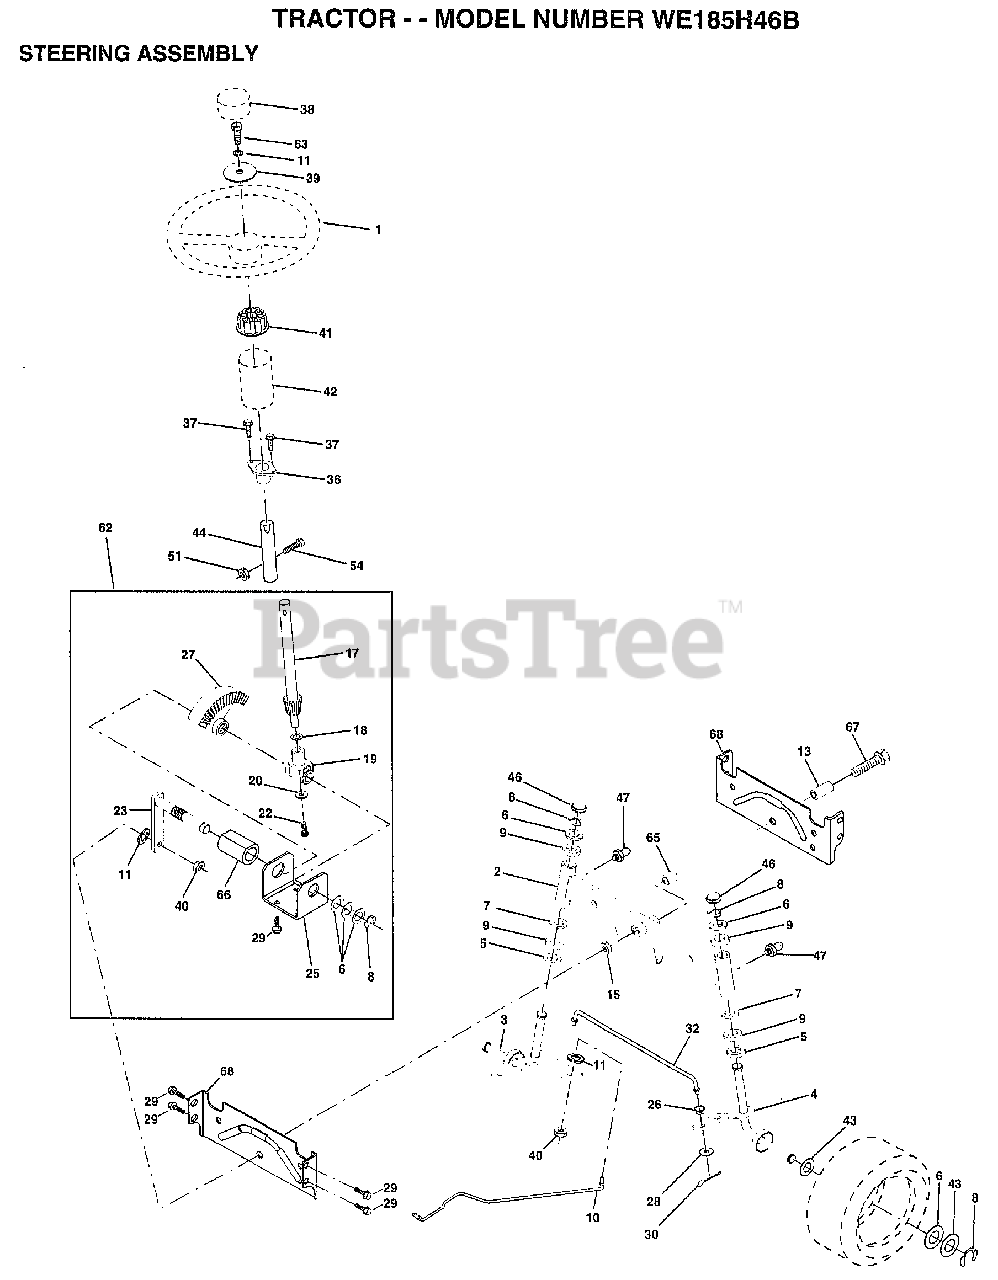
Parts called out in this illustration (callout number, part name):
1	WHEEL STR AYP BLK
2	AXLE ASM
3	SPINDLE.ASM.LH
4	"SPINDLE ASM,RH"
5	WASHER .T
6	WASHER
7	WASHER
8	RING
9	COL. SRTG. BEAR.
10	DRAGLINK-STAMPED
11	LOCKWASHER
13	BEARING AXLE
15	"NUT-LOC,FLANGE LT"
17	SHAFT ASM STEERIN
18	THRUST WASHER
19	SUPPORT.SHAFT
22	SCREW HEX SOC1/4-
25	BRKT-STEERING
26	BUSHING.DRAGLINK
27	GEAR SECTOR
28	WASHER
29	SCREW
30	COTTER PIN
32	TIE ROD
36	BUSHING.STEERING
37	"SCREW-TT,10-32 FL"
38	CAP STEER AYP
39	WASHER T
40	GRIPCO NUT
41	ADAPTER LT
42	BOOT.STEER.PL
44	EXT SHAFT STEERIN
46	CAP
47	ZERK M
51	NUT
54	BOLT
62	KIT STEERING ASM
63	BOLT
65	SPACER AXLE
66	"BEARING-ARM,PITMA"
67	BOLT
68	BRACE AXLE
